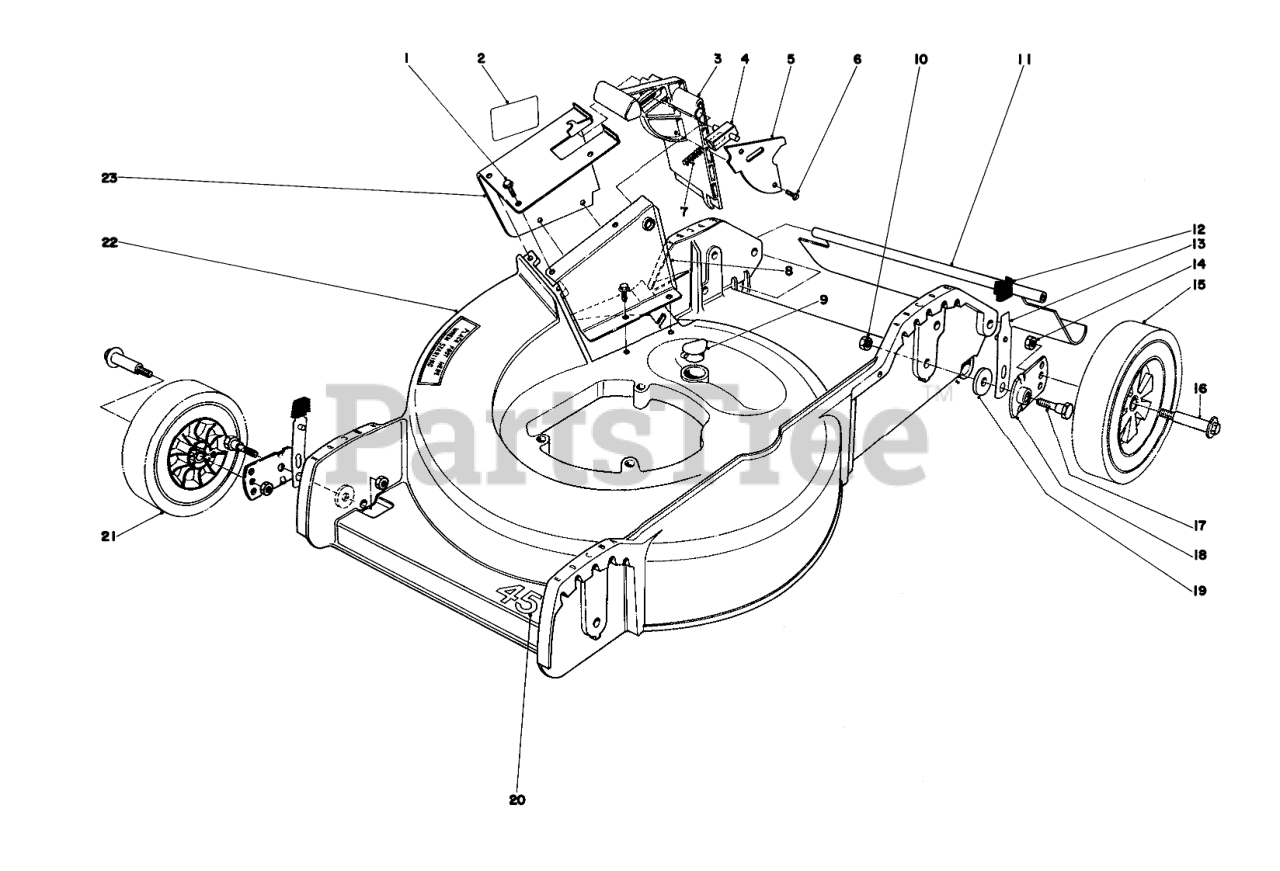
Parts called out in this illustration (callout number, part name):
1	SCREW
2	Decal-Door
3	Door Mulching
4	Door Latch
5	Cover Door
7	SPRING-COMPRESSION, LATCH
8	Inner Tunnel
9	WASHOUT PLUG
10	Nut
11	SHIELD - TRAILING
12	KNOB-ARM
13	SPRING ARM ASM
14	Nut
15	WHEEL & TIRE ASM
16	BOLT-WHEEL
17	PIVOT SCREW
18	PIVOT ARM ASSY
19	PIVOT WASHER
20	Decal
21	Wheel & Tire Assembly
22	Housing
23	Tunnel Outer
